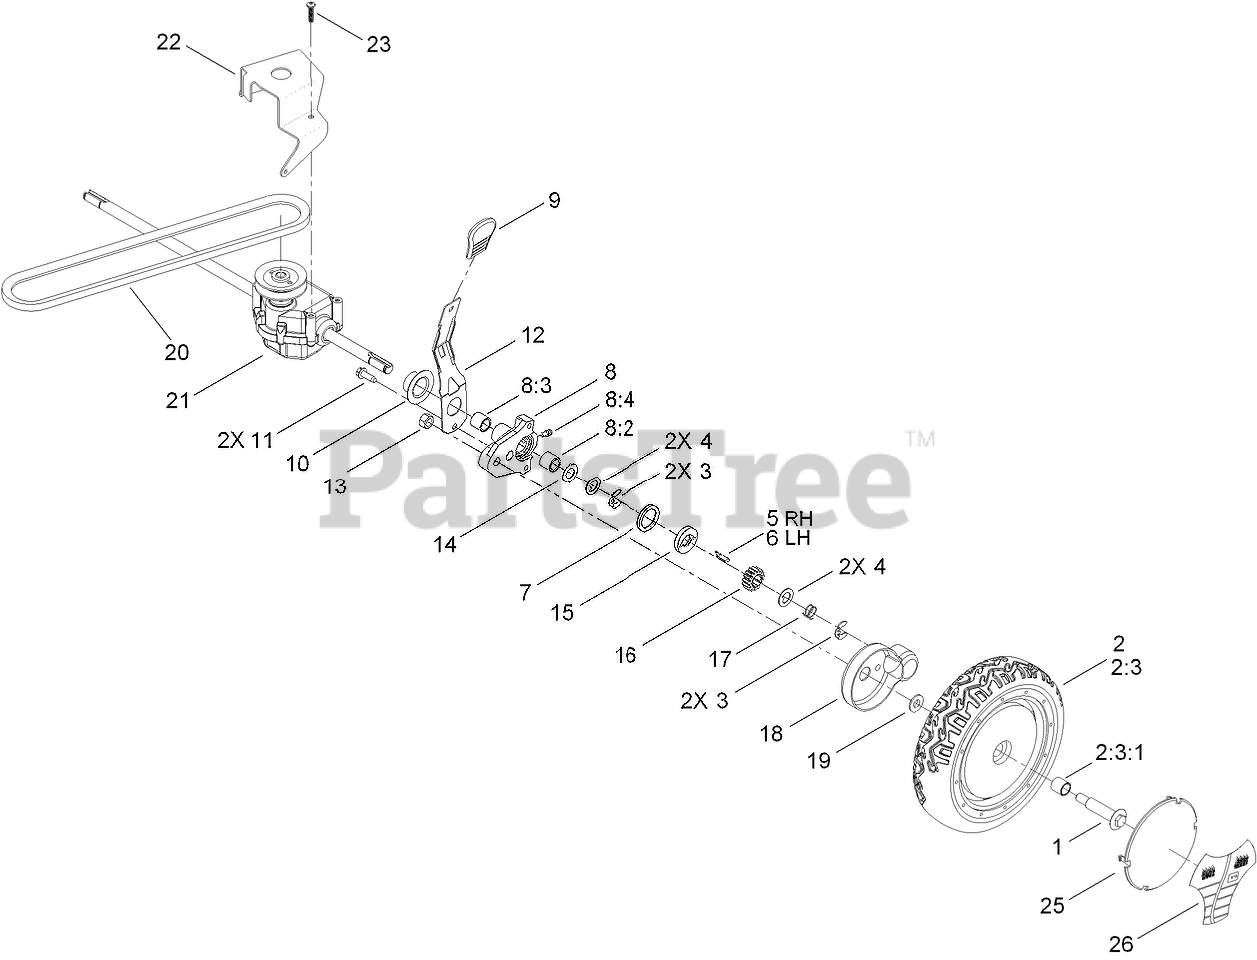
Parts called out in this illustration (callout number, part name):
1	BOLT-SHOULDER
2	8 INCH WHEEL AND GEAR ASM
2:3	8 INCH WHEEL ASM
2:3:1	BUSHING
3	RING-CLIP, LOCKING
4	WASHER-THRUST, KEYED
6	KEY-ROCKING, LH
7	RING-FRICTION
8	PIVOT ARM ASM
8:2	BUSHING
8:3	BUSHING
8:4	FITTING-GREASE
9	KNOB-HOC
10	CAP-END
11	SCREW-HWHTF
12	ARM-SPRING
14	WASHER-ARM, PIVOT
15	WASHER-CLUTCH
16	GEAR-PINION
17	SPRING-COMPRESSION
18	COVER-WHEEL
19	SPACER-COVER, WHEEL
20	V-BELT
21	TRANSMISSION ASM
22	BRACKET-TRANSMISSION
23	SCREW-PLASTITE
25	COVER-WHEEL
26	LABEL-WHEEL, SMART
